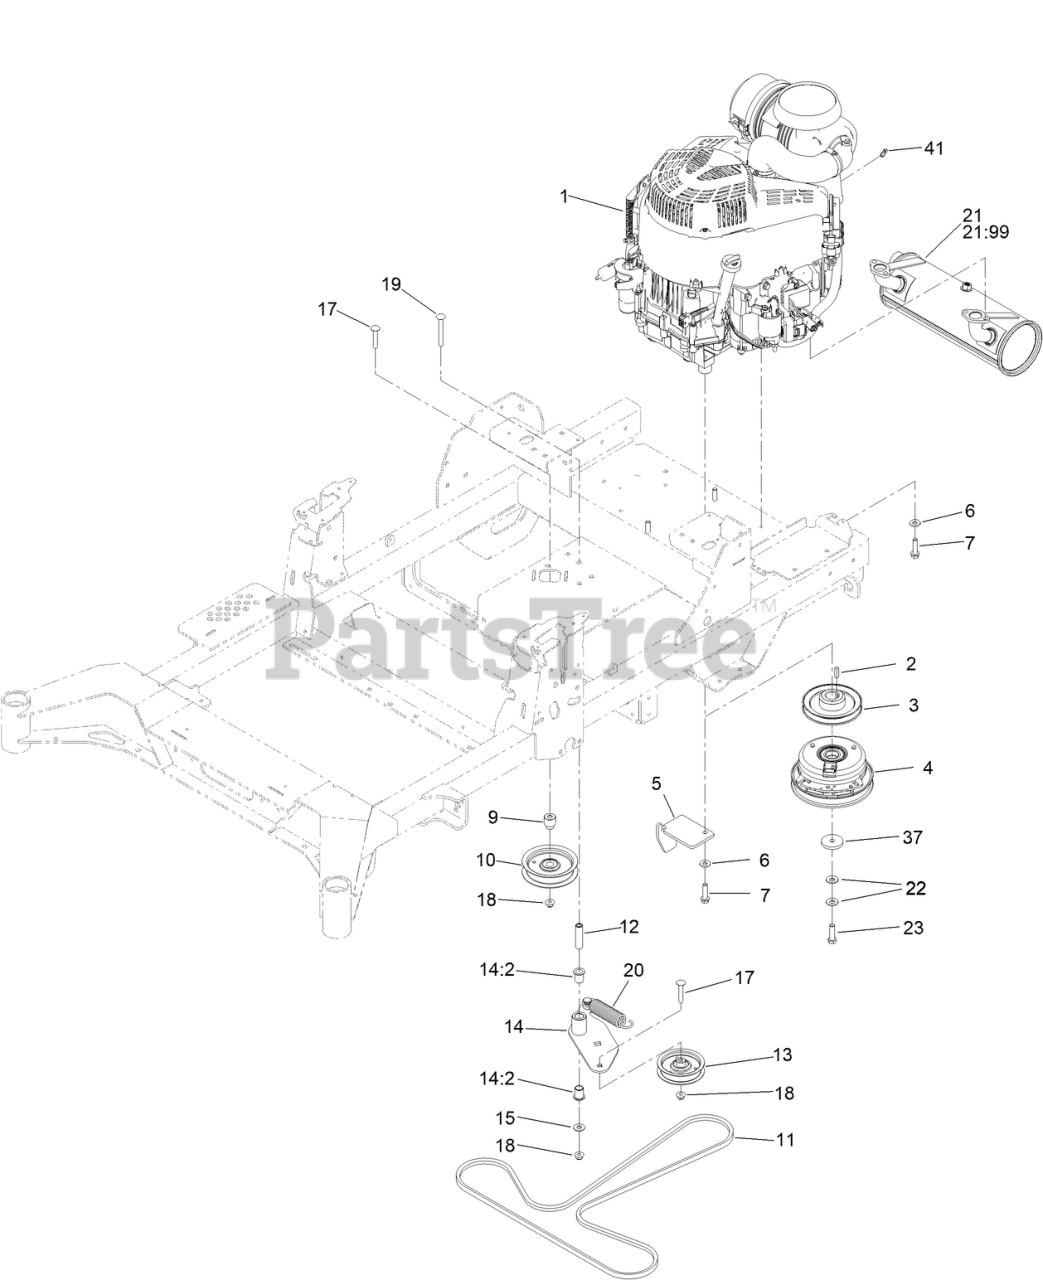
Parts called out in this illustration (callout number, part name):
1	ENGINE 810 VANGUARD EFI
3	SHEAVE (W/HUB)
4	CLUTCH 6.75, 105 FTLB, 1.125 DD
5	ANCHOR-CLUTCH
6	WASHER-BELLEVILLE
7	SCREW-HWH
9	BUSHING-IDLER
10	PULLEY-IDLER, FLAT
11	BELT-V
12	BUSHING, IDLER PIVOT
13	PULLEY-IDLER, FLAT
14	IDLER ARM ASM
14:2	BUSHING-FLANGE
15	WASHER-FLAT
17	BOLT-CARRIAGE
18	NUT-HF, NI
19	SCREW-CARR
20	SPRING-EXTENSION
21	MUFFLER ASM-BRIGGS
21:99	SPARK ARRESTOR, 1.5"
22	WASHER-SPRING
23	SCREW-HH, W/LOCTITE
37	WASHER-CLUTCH
41	TIE-CABLE
